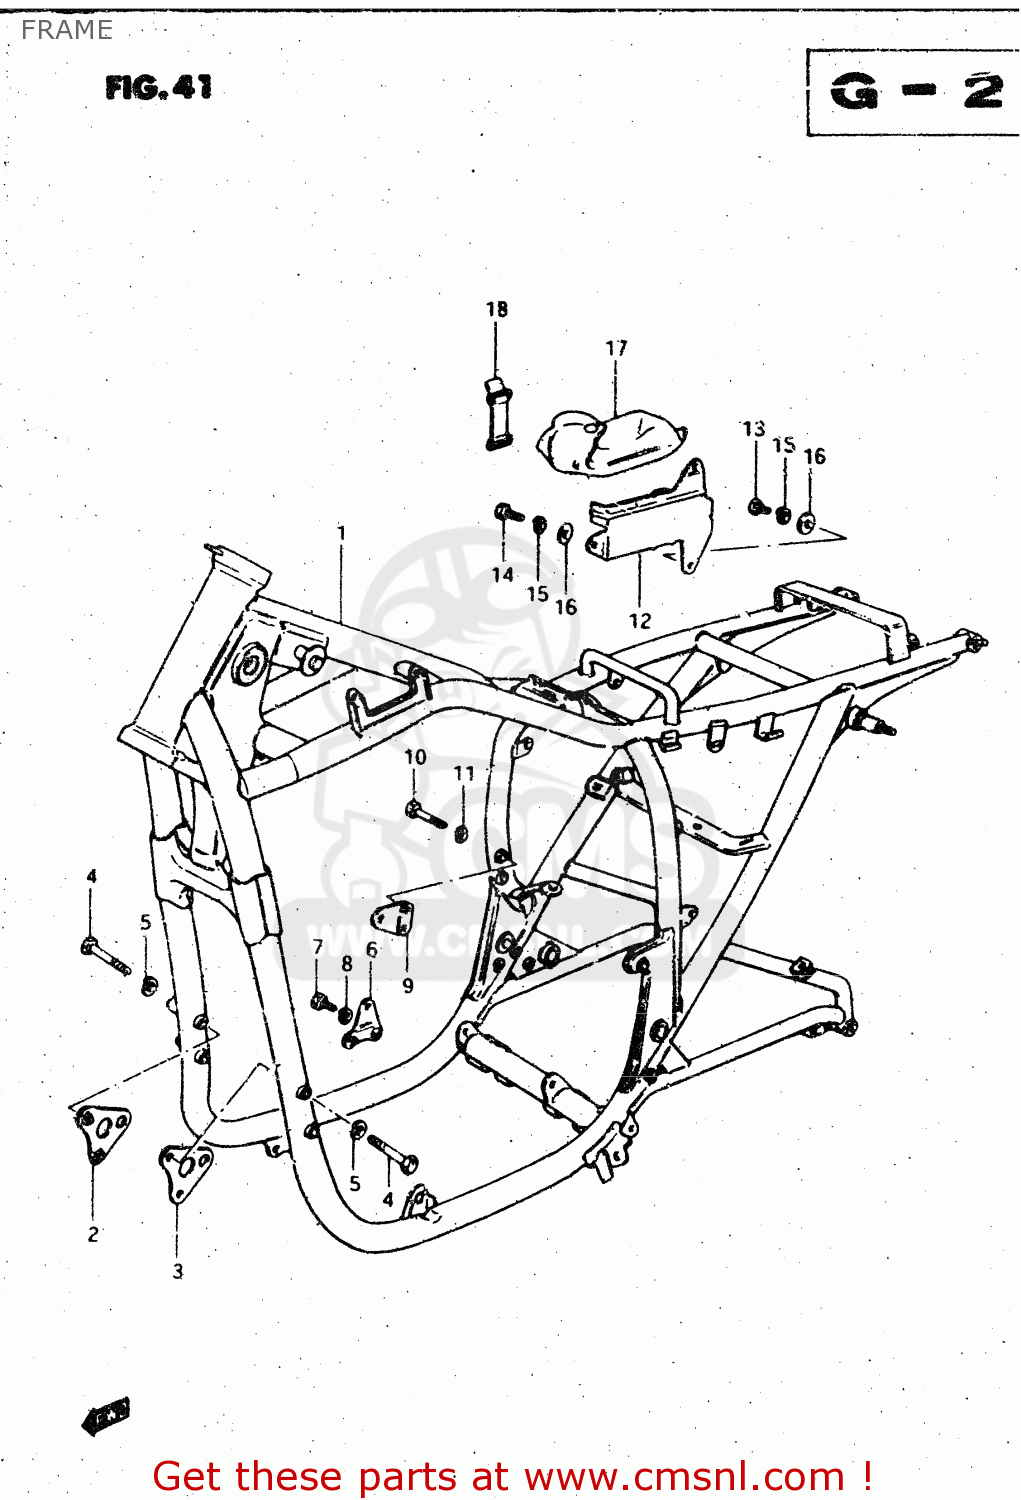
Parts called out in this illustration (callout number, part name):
1	FRAME (BLACK)
2	PLATE,ENGINE MOUNTING
3	PLATE,ENGINE MOUNTING
4	BOLT
5	LOCK WASHER
6	PLATE,ENGINE MOUNTING
7	BOLT
8	LOCK WASHER
9	PLATE,ENGINE MOUNTING
10	BOLT 8X45
11	LOCK WASHER
12	HOLDER,TOOL
13	SCREW 6X12
14	SCREW
15	LOCK WASHER
16	WASHER
17	TOOL SET
18	BAND
